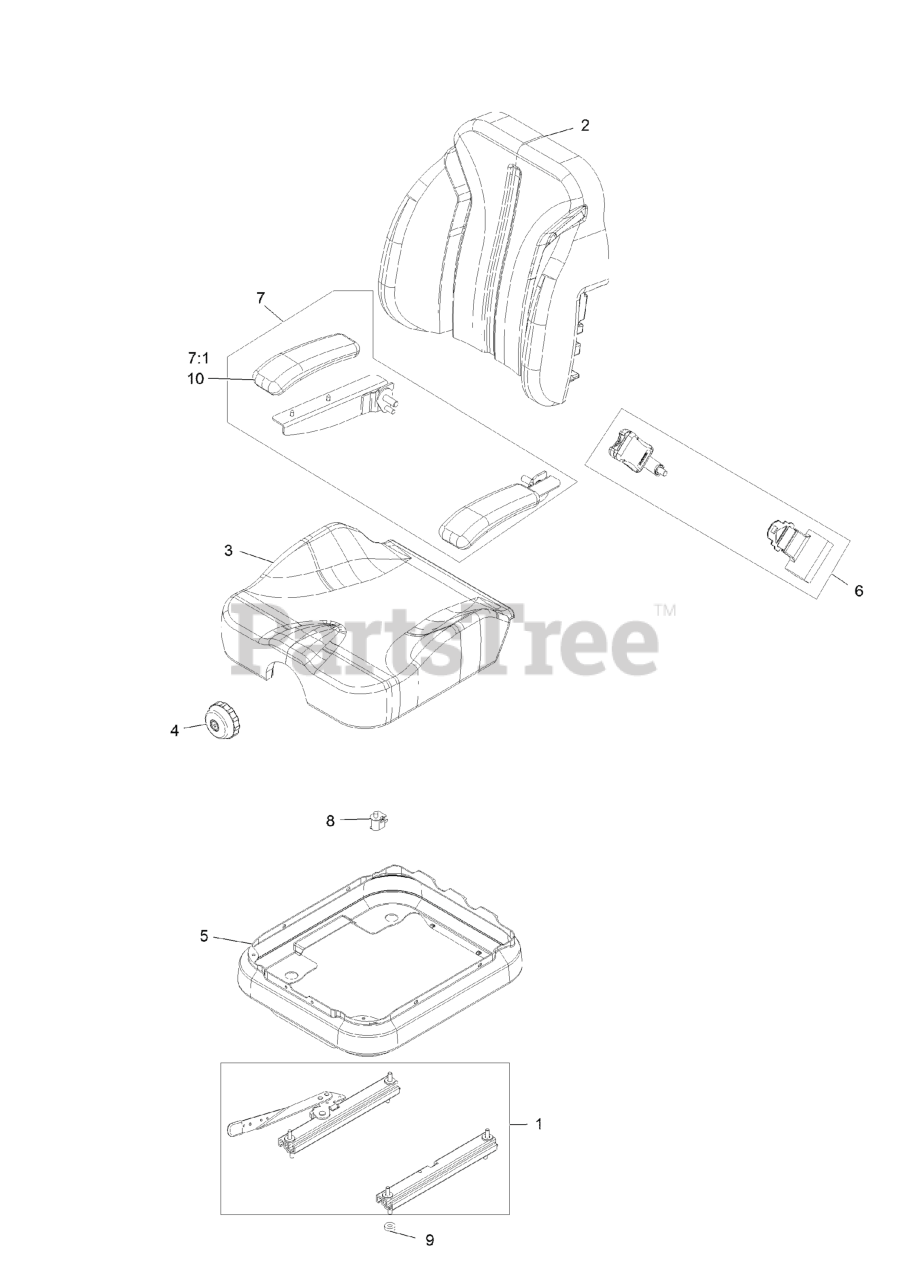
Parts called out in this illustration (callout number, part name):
1	TRACKS-4" TRAVEL
2	COVER-SEAT BACK SVC
3	COVER-SEAT BOTTOM SVC
4	KNOB-ADJUSTER
5	BELLOWS-SEAT
6	KIT-SEAT BELT
7	ARMREST KIT
7:1	CUSHION-REST, ARM
8	SWITCH-BAIL
10	CUSHION-REST, ARM
